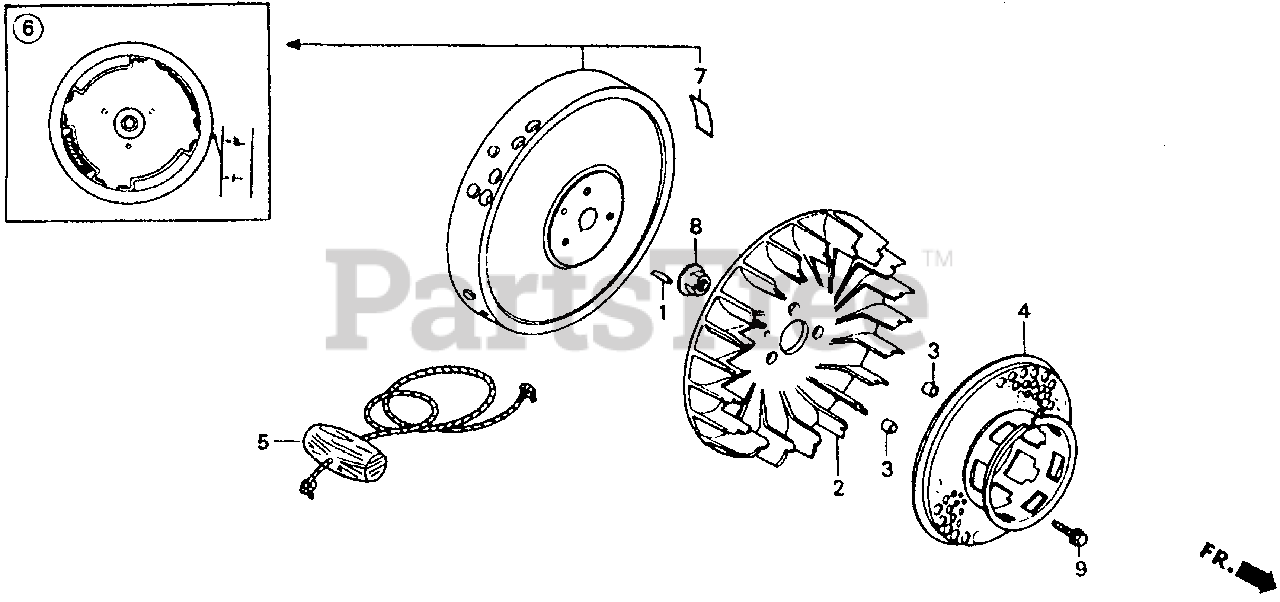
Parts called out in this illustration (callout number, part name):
1	KEY, SPECIAL WOODRUFF (25X18)
2	FAN, COOLING
3	COLLAR, FAN
4	PULLEY, STARTER
5	ROPE, STARTER (#5X55")
6	FLYWHEEL
7	MARK, FLYWHEEL CAUTION
8	NUT, SPECIAL (14MM)
9	BOLT, FLANGE (6X16)
